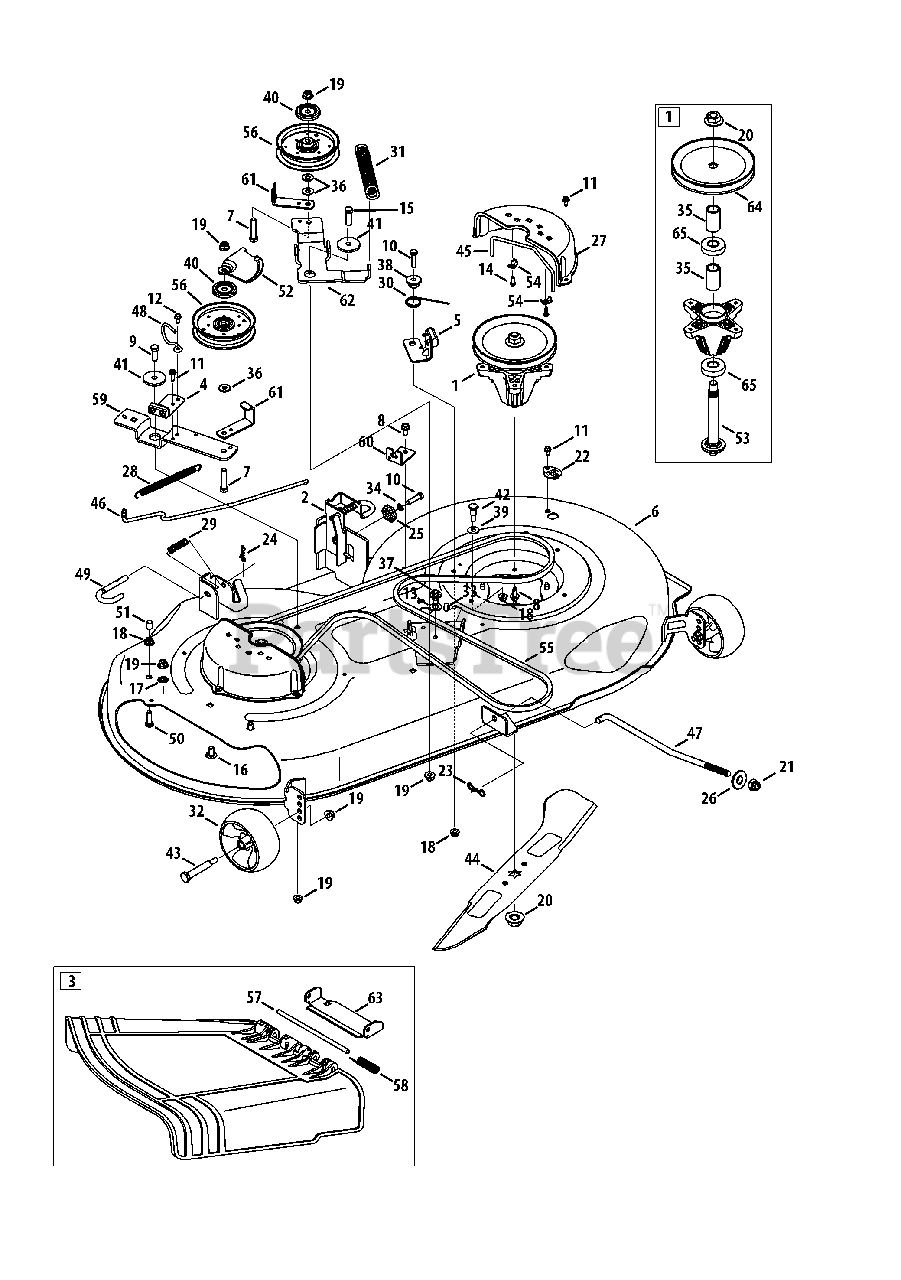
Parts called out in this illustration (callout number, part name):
1	Spindle Assembly, Pul 6.93 Dia
2	Bracket Assembly, Deck Hanger, LH
3	Chute Deflector Assembly
4	Brake Assembly, Deck, 46
5	Brake Assembly, Deck, 46"
6	Deck Assembly, 46t, 2w
7	Hex Screw, 3/8-16 x 2.00
8	Screw, Self-tapping, 5/16-18, .750
9	Hex Screw, 3/8-16, 1.00, Gr5, Std
10	Hex Screw, 5/16-18, 1.25, Gr5, Std
11	Screw, Self-tapping, 1/4-20, 0.500
12	Screw, Self-tapping, 1/4-20, .750
13	Washer, Flat, .474 x .879 x .064
14	Screw, B, #10-16, 0.625
15	Hex Screw, 3/8-16 x 1.25
16	Bolt, Carriage, 3/8-16, 0.75, Gr1
17	Nut, Push, 3/8
18	Nut, Flange Lock, 5/16-18, Nylon
19	Nut, Flange Lock, 3/8-16, Nylon
20	Nut, Flange, 5/8-18
21	Nut, Lock, 1/2-13
22	Deck Wash Plug
23	Bow-Tie Cotter Pin
24	Bow-Tie Cotter Pin, 72
25	Gear, Deck Adjustment
26	Pivot Cup, Deck List
27	Belt Cover, Universal
28	Spring, Extension, .62 x 6.12
29	Spring, Compression, .535 x 1.751
30	Spring, Torsion, .992 I.D X 1.17 O.D
31	Spring, Extension, 1.05 X 6.346
32	Wheel, Deck, 5.0 Dia Ball
33	Bumper, .62 Dia X .3
34	Washer, Lock, 5/16, Regular Duty
35	Spacer, .792 X 1.060 X 1.860 LG
36	Washer, Flat, .385 x .870 x .092
37	Shoulder Spacer, .43 x .29, 5/16-18
38	Shoulder Spacer, .50 x .145
39	Washer, Flat, .343 X .880 X .062
40	Pulley Cap
41	Shoulder Spacer, .8840 X .190
42	Shoulder Screw, .437 Dia. X .54
43	Bolt, Shoulder, .496 x 2.50, 3/8-16
44	Blade, Cut, 23.25" 2-In-1, Econ
45	Rod, Keeper, Belt
46	Rod, Control, Brake 46"
47	Rod, Lift, Deck, Medium
48	Rod, Keeper, Belt, 42s 46t
49	Rod, Deck Release
50	Hex Cap Screw, 5/16-18 x 1.00
51	Cap, .290 x .500
52	Belt Guide
53	Spindle Shaft, 6.05 LG.
54	Clamp, Casing
55	Belt, V-Typ, A Sec
56	Pulley, Idler, 4.25"Dia
57	Hinge Pin
58	Torsion Spring
59	Bracket, Idler, Pivot, 46
60	Bracket, Cable, Deck Engagement
61	Bracket, Guard, Belt, 4.25 Pulley
62	Bracket, Idler, 46" Lh
63	Chute Bracket
64	Deck Pulley, 6.93 DIA
65	Ball Bearing, .787ID X 1.85 ODX.551
